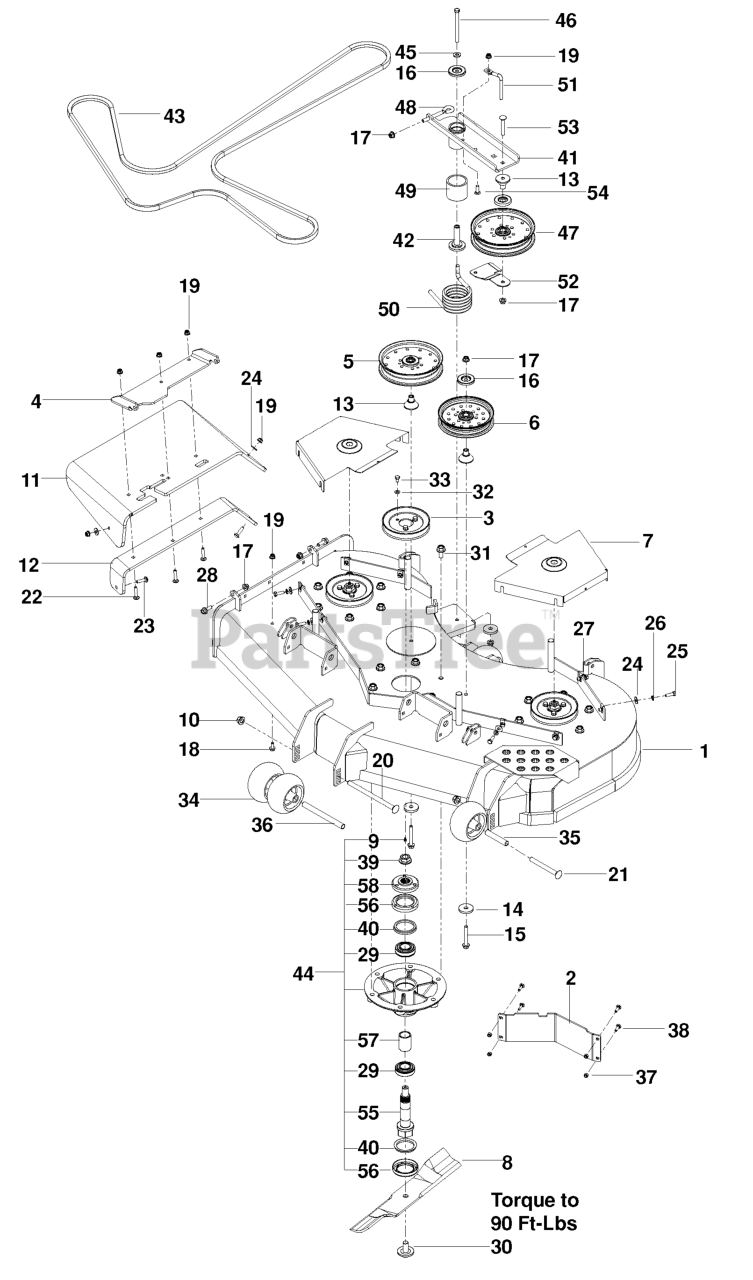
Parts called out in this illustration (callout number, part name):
1	DECK.FAB.54".W/DECALS.ORANGE
2	BAFFLE, DIVERTER 54"/60" LH
3	PULLEY - 5.93 OVER PINS
4	BRKT - CHUTE MTG BLACK
5	PULLEY - 7" NARROW
6	PULLEY IDLER, 6" NARROW
7	SHIELD,BELT, 60" ORANGE
8	BLADE, 19"
9	ZERK
10	NUT, 1/2-13 HEX FLG NYLOC ZD
11	CHUTE, DISCHARGE 48-52
12	BRKT, CHUTE SUPPORT BLACK
13	BEARING, IDLER ARM
14	SPINDLE WASHER
15	HHFS 3/8-16 X 2 3/4
16	DUST SHIELD
17	NUT 3/8-16 HEX FLG NYLOC ZD
18	HHFS 5/16-18 X 3/4
19	5/16-18 NYLOC FLANGE NUT
20	RHSNB 1/2-13 X 8 GR5 ZD
21	RHSNB 1/2-13 X 4.75 GR5 ZD
22	RHSNB 5/16-18 X 1-1/2 GR 5 ZD
23	BOLT, CARRIAGE 5/16X1-1/4
24	WASHER 5/16 FLAT
25	HCS 5/16C X 1
26	WASHER.LOCK.HVY.HLCL.SPR.5/16
27	U-CLIP 5/16-18 NUT RETAINER
28	HHFS 3/8-16 X 1 GRD 5 ZD
29	BEARING - 206KRR8
30	BLADE BOLT/WASHER
31	HHFS 1/2-13 X 1 GR5 ZD
32	WASH 5/16 DISC SPRING ZD
33	HCS 5/16-18 X 1/2 GR 5 ZD
34	ROLLER, GAUGE .635 BORN
35	TUBE, ROLLER AXLE
36	TUBE, ROLLER AXLE LONG
37	NUT.1/4-20.HEX.NYLOC.ZD
38	1/4-20X3/4 CARR BLT
39	NUT FLANGE 3/4-16
40	V-RING, 55MM
41	ASSY, IDLER ARM, PZ
42	BEARING, IDLER PIVOT
43	BELT, "B", 169.75
44	SPINDLE ASM. 10"
45	WASHER, 3/8 THICK
46	HCS 3/8-16 X 4-1/2 GR 8 ZD
47	PULLEY - IDLER 7"
48	EYE BOLT, 3/8 X 4"
49	SPACER, IDLER PIVOT
50	SPRING, TORSION, IDLER
51	BELT KEEPER
52	BELT.GUIDE.BLACK
53	CARRIAGE BOLT 3/8-16 X
54	RHSSNB 5/16C X 1.0
55	SHAFT - SPINDLE
56	CUP - DEBRIS
57	SPACER - BEARING
58	HUB - PULLEY
